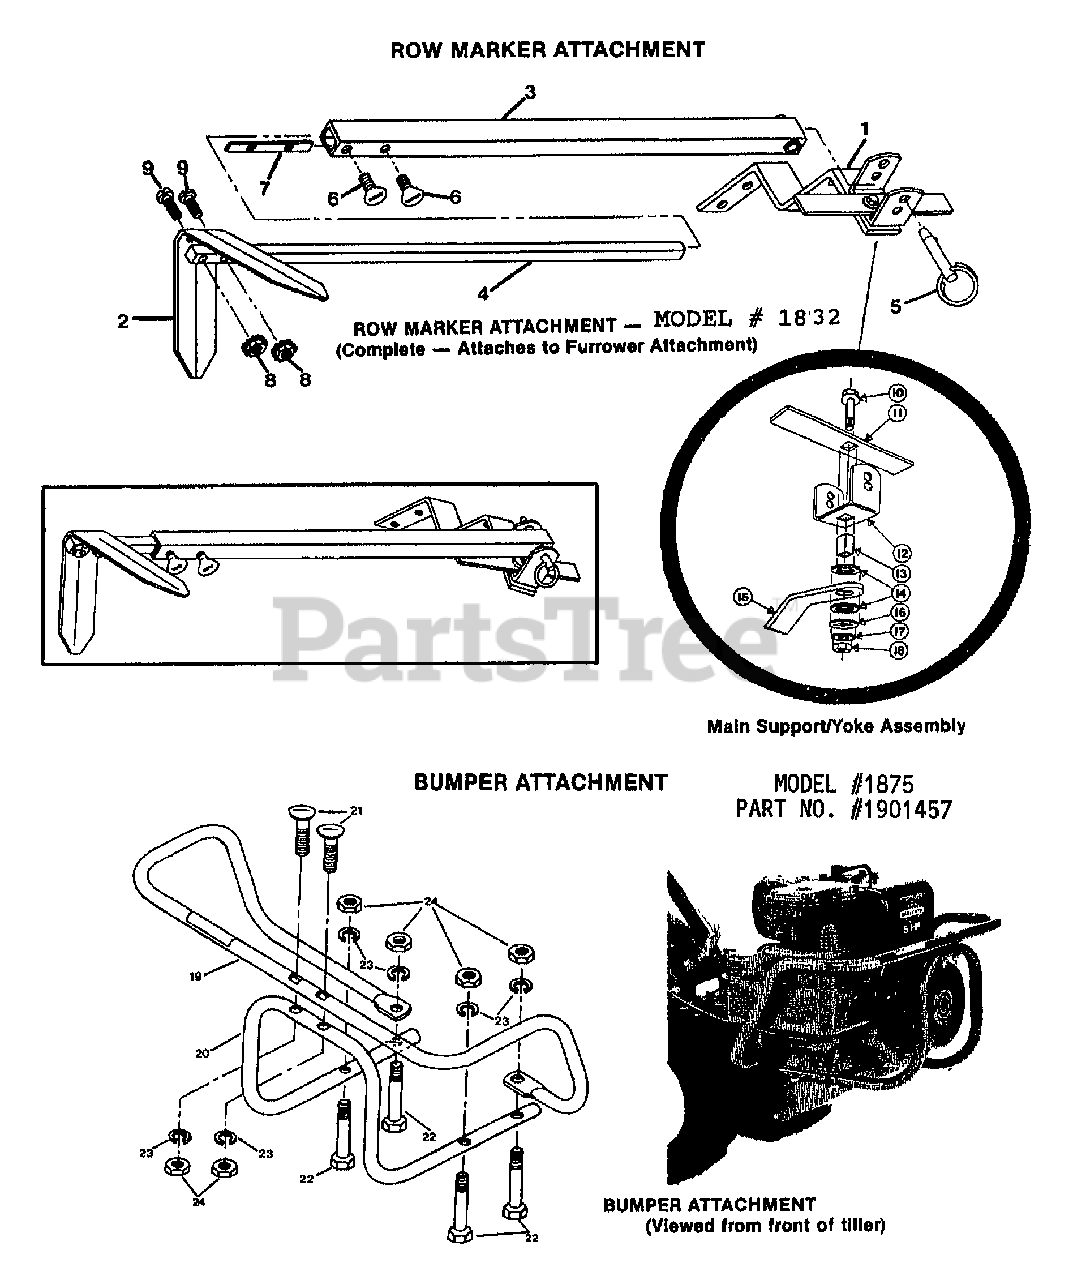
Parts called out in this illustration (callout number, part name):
1	ASSM-MAIN SUPT PAINT
2	MARKER-ROW MARKER
3	MARKER ARM-WELD PAINT
4	ASSM-MARKER ARM EXT-PAINT
5	PIN # COTTERLESS HITCH ZP
6	SCR-THUMB 1/4-20 X .75 ZP
7	BAR-NUT
8	NUT W/LKWASHER 10-24 ZP
9	SCR-RH M10-24X1.0 NC-2A
10	SCR-HFLK 3/8-16X1.50
11	BAR-STOP
12	YOKE-ROW MARKER
13	TUBING-SQ .5 X .907
14	WASHER-.375X.51X.125
15	SUPT-MAIN ROW MARKER
16	WASHER-SQ HOLE 1.38X5SQX.12
17	WASHER-.994X.413X.145
18	NUT-HEX 3/8-16 ZP
19	BUMPER TOP SECTION
20	BUMPER-BOTTOM SECT.PNT
21	BOLT-CH 5/16-18 X 2 ZP
22	SCR-HH 5/16-18X2.5
23	WASHER-LK .312 ZP
24	NUT-HEX 5/16-18 ZP
